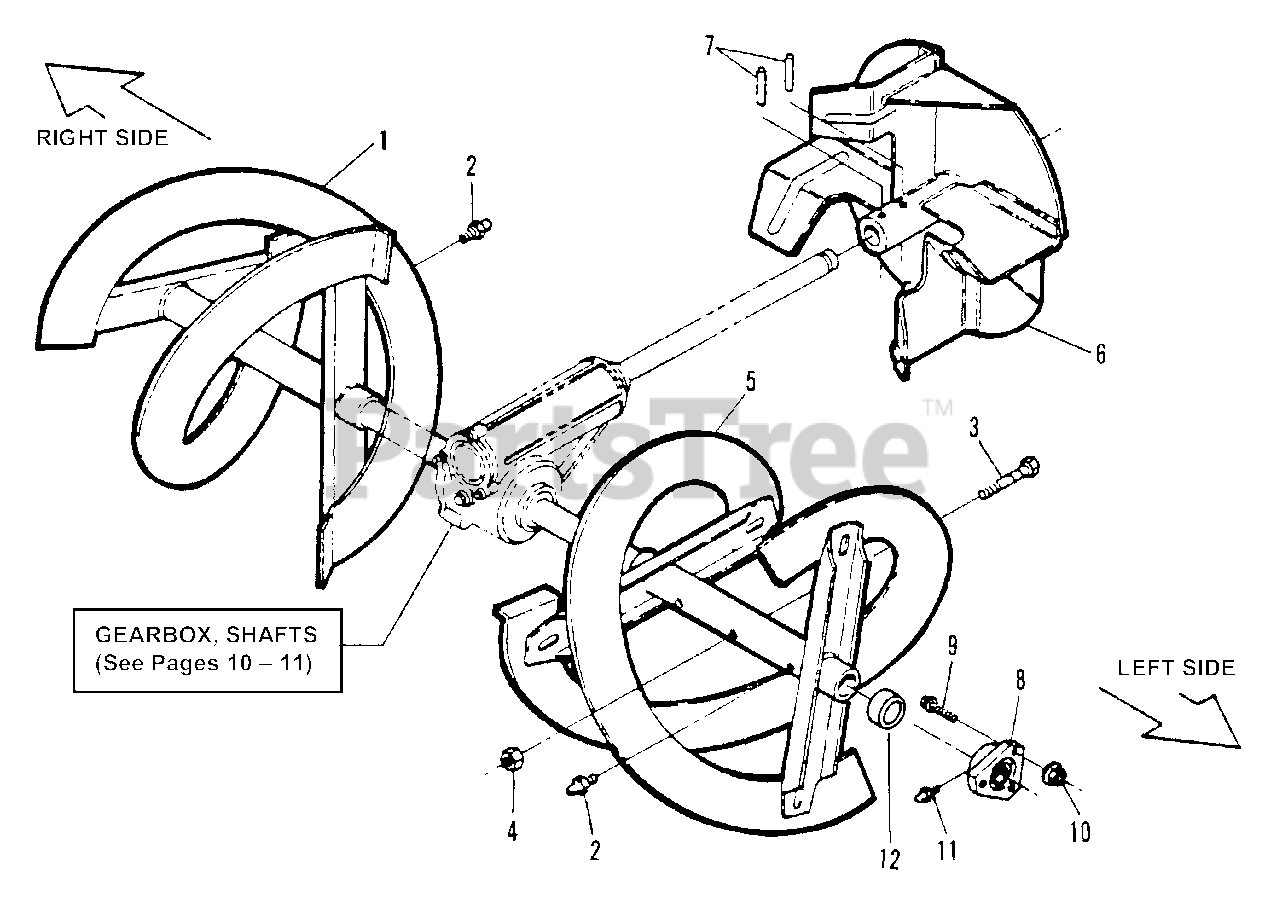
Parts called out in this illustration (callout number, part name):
1	AUGER, Right Side (Weldment)
2	LUBE FITTING, Straight (press-fit for .187 dia. Hole)
3	BOLT, 5/16-18 x 1-7/8" Shear
4	NUT, 5/16-18 Hex Nyloc
5	AUGER, Left Side (Weldment)
6	FAN, Impeller (Weldment)
7	PIN, 1/4 x 1-1/2" Roll
8	ASSEMBLY, Bearing
9	BOLT, 1/4-20 x 3/4" Hex Flange Lock, Grade 5
10	NUT, 1/4-20 Hex Flange Lock
11	FITTING, Lube (Press fit for .187 hole-no ball)
12	SPACER
